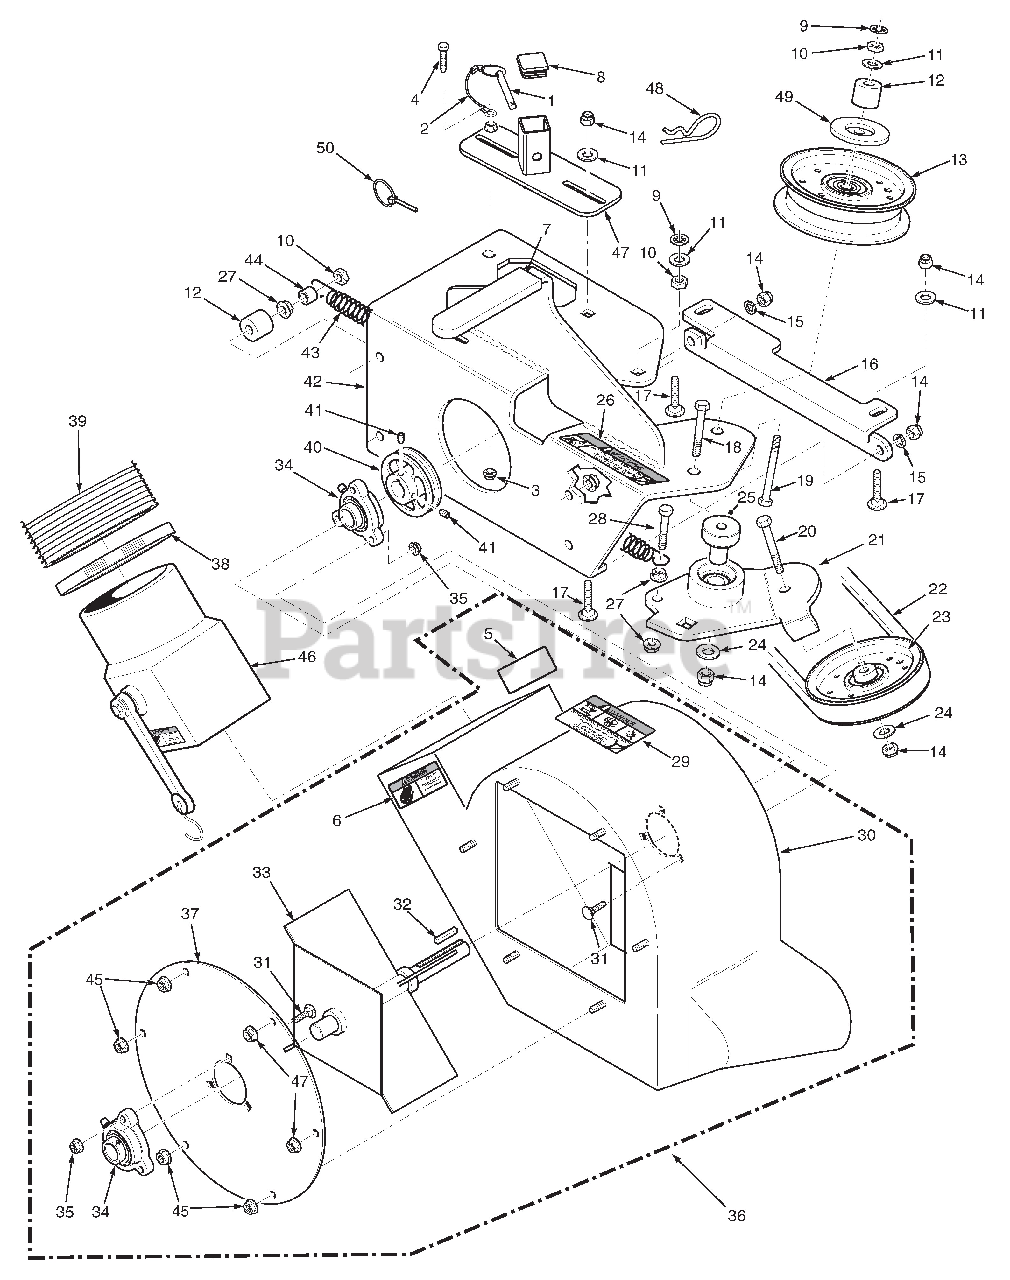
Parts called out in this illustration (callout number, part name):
1	Pin, Ring 2-1/4" Long
2	Lanyard, Deck Height Pin
3	Nut, Serr. Flange 1/4-20
4	Bolt, Hex Head 1/4-20 x 1-1/4"
5	Decal, Blower
6	Decal, Rotating Blower
7	Grip, Blower Lever
8	Cap, Square
9	Nut, Push On 3/8 Thread
10	Lock Nut, 3/8-16
11	Flatwasher, 3/8-.391 x .938 x .105
12	Spacer
13	Pulley, Idler 3-1/2" Dia. - 52"
14	Nut, Elastic Stop 3/8-16
15	Lockwasher, 3/8-16
16	Plate, Catcher Mounting
17	Bolt, Carr. 3/8-16 x 1-1/2"
18	Bolt, Hex Head 3/8-16 x 3" - 52"
19	Bolt, Hex Head 3/8-16 x 3-1/2"
20	Bolt, Hex Head 3/8-16 x 1-3/4"
21	Idler Arm Assembly - 52"
22	Belt, GC-STT-52v
23	Pulley, 3-1/2" O.D., GC-STC
24	Washer, 3/8 Hardened
25	Pivot, Idler Long - 52"
25	Pivot, Idler - 61"
26	Decal, Belt Cover
27	Nut, Serr. Flange 3/8-16
28	Bolt, Hex Head 3/8-16 x 1-1/2 Gr. 8
29	Decal, Danger
30	Blower Housing Weldment w/Decals
31	Bolt, Carr. 5/16-18 x 3/4" Gr. 5
32	Key, 1/4 x 1/4 x 1-1/2"
33	Fan Weldment
34	Bearing Assembly
35	Nut, Elastic Stop 5/16-18
36	Blower Housing Assembly, GC-STT
37	Cover, Blower Housing
38	Clamp, 8-5/8" Max Dia.
39	Hose, 8.00" Dia. x 60.50" Long
40	Pulley, 4-3/4" O.D. - 1" Bore
41	Set Screw, 5/16-18 x 3/8"
42	Frame, Blower Mount
43	Spring, Main Drive
44	Spacer
45	Nut, Serr. Flange 5/16-18
46	Adapter w/Strap
47	Receiver Weldment, Mount Post - 52"
47	Receiver Weldment, Mount Post - 61"
48	Hair Pin Cotter, .177 x 3-1/4"
49	Dust Shield
50	Quick Pin, 5/16" Dia.
